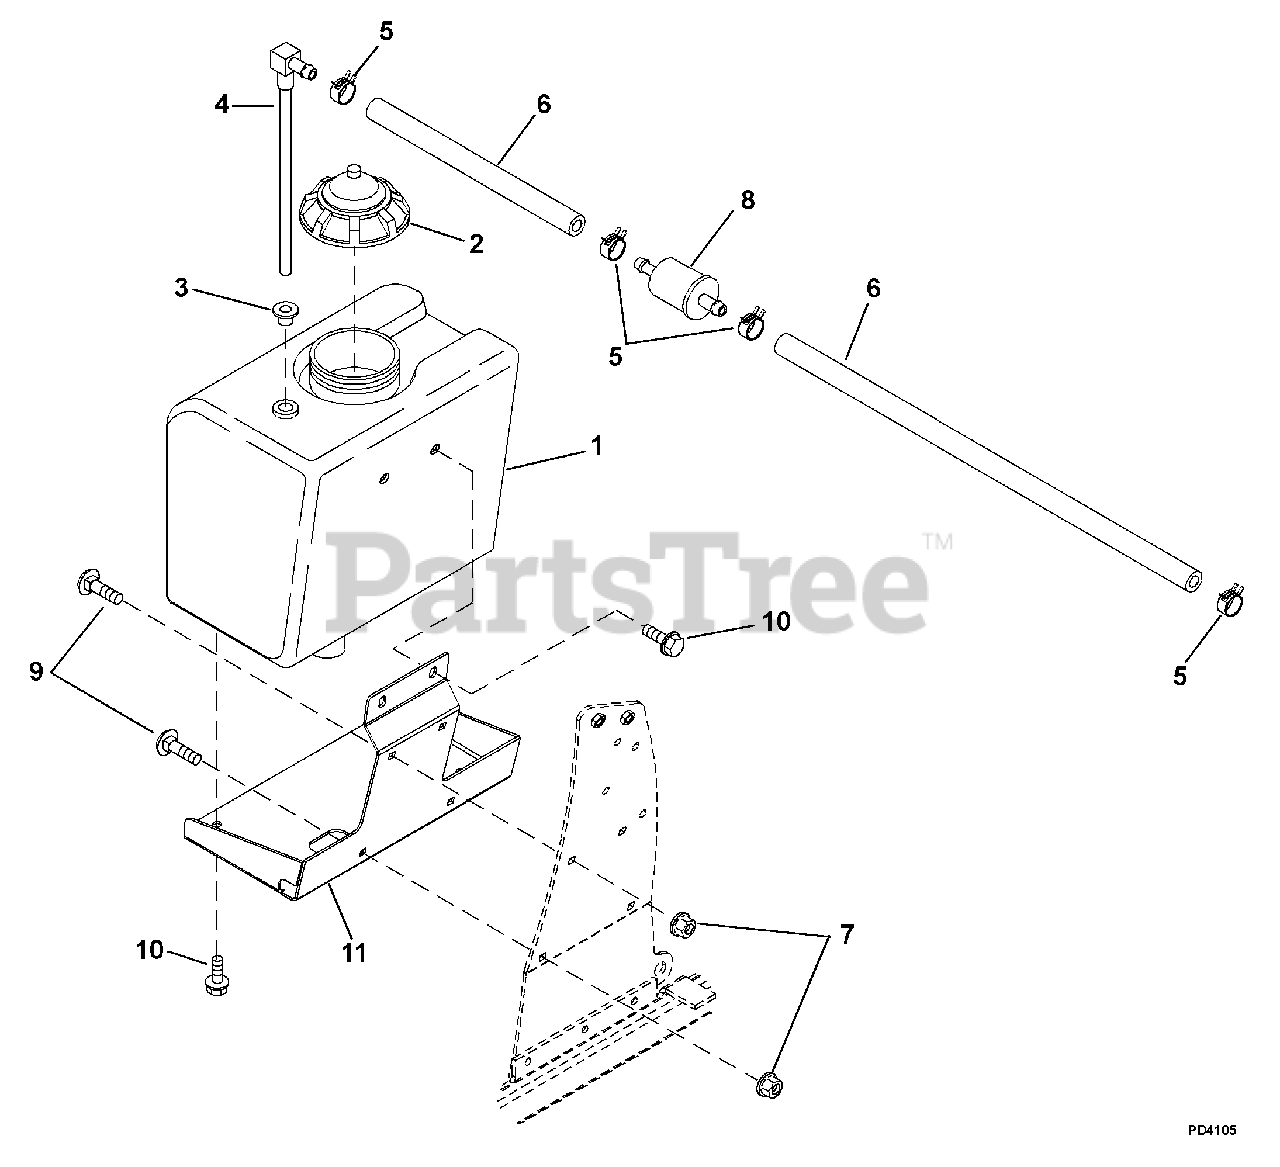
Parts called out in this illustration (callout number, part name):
1	TANK-FUEL 48P/S W/CAP W/O LOGO
2	CAP, FUEL S/O
3	GROMMET
4	FUEL PICKUP
5	CLAMP
6	HOSE, .25 LOW-PERM BULK GAS
7	@NUT-LK-NYL .38-16 YWZC
8	FUEL FILTER - KAWASAKI
9	@BLT-RDHDSHSQNK.38-16X1.0 G5YZ
10	SCREW,HEX,FL,JDS123,M8X1.25X16
11	BRACKET, FUEL TANK MOUNTING
